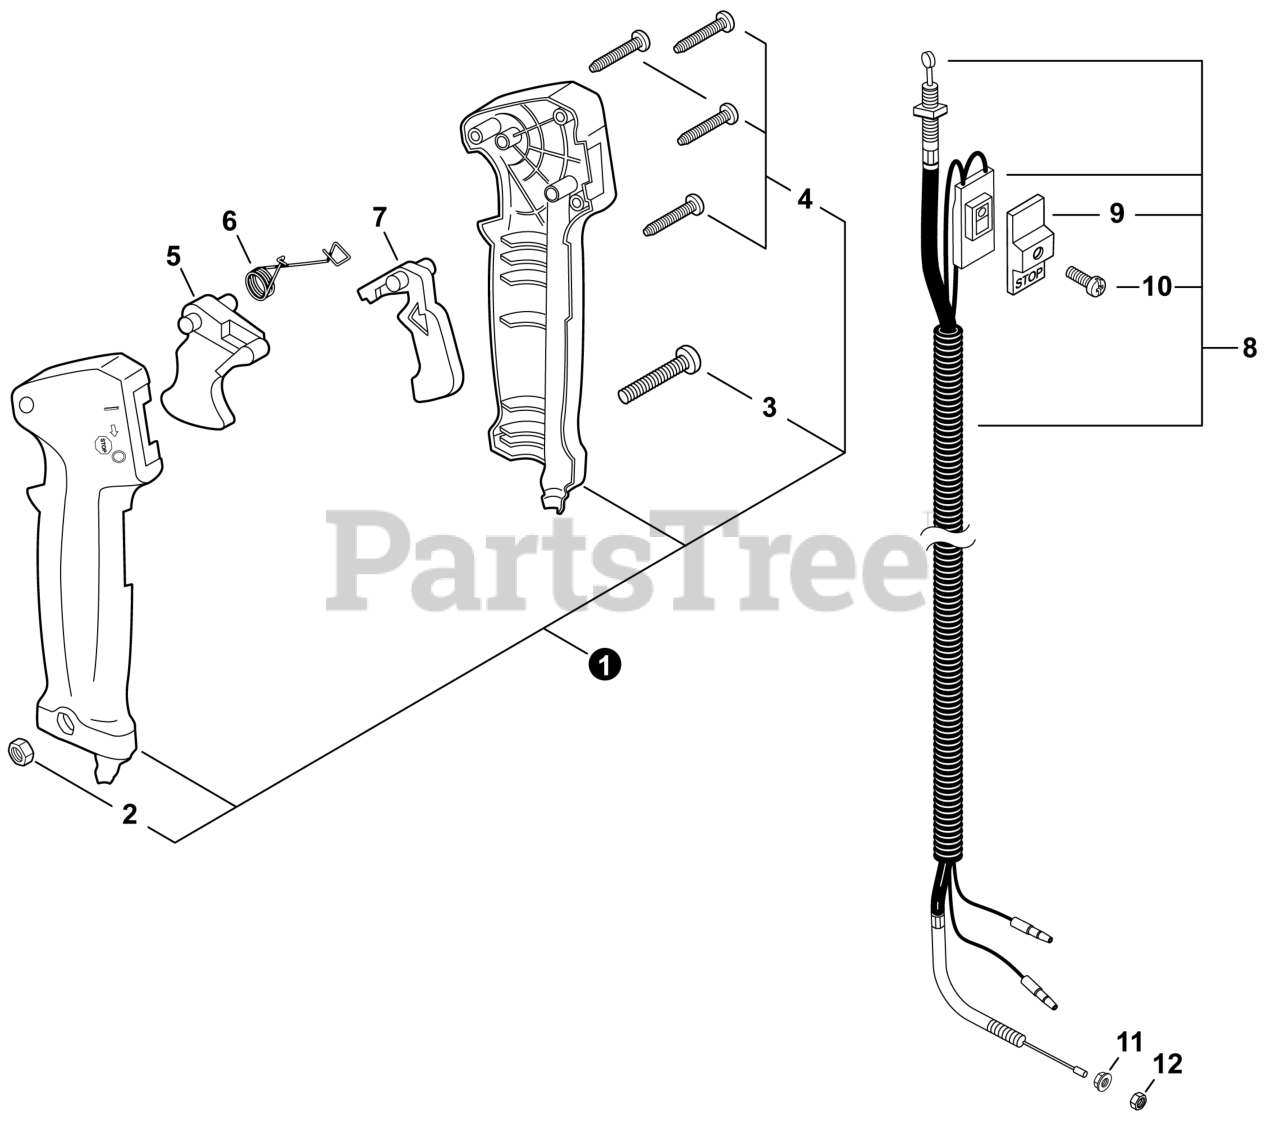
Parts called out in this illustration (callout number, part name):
1	CONTROL HANDLE KIT
3	SCREW 5x30
4	SCREW 3x25
5	TRIGGER, THROTTLE
6	SPRING, TORSION
7	LOCKOUT, THROTTLE
8	CABLE ASSY, CONTROL
9	KNOB, SWITCH - ORANGE
10	SCREW 3x10
11	NUT, FLANGE M6
